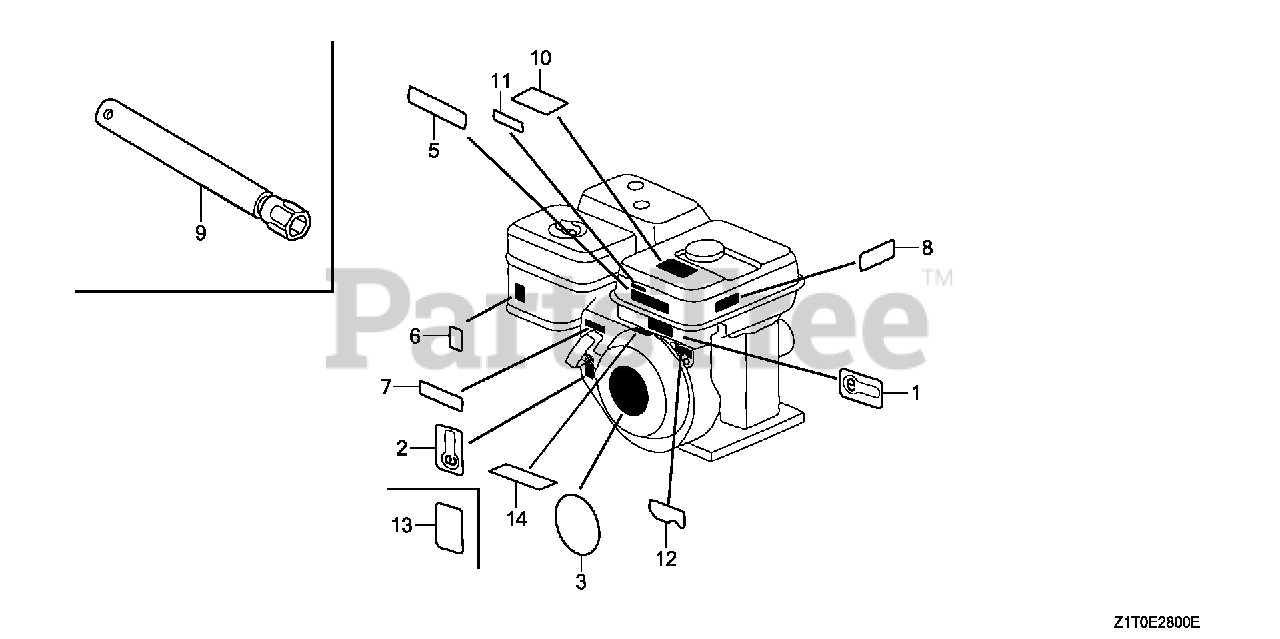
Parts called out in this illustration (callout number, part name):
3	EMBLEM (GX160 5.5)
5	LABEL, CAUTION
6	MARK, CHOKE
8	MARK, OIL ALERT (ENGLISH)
11	LABEL, CAUTION (CHINA)
